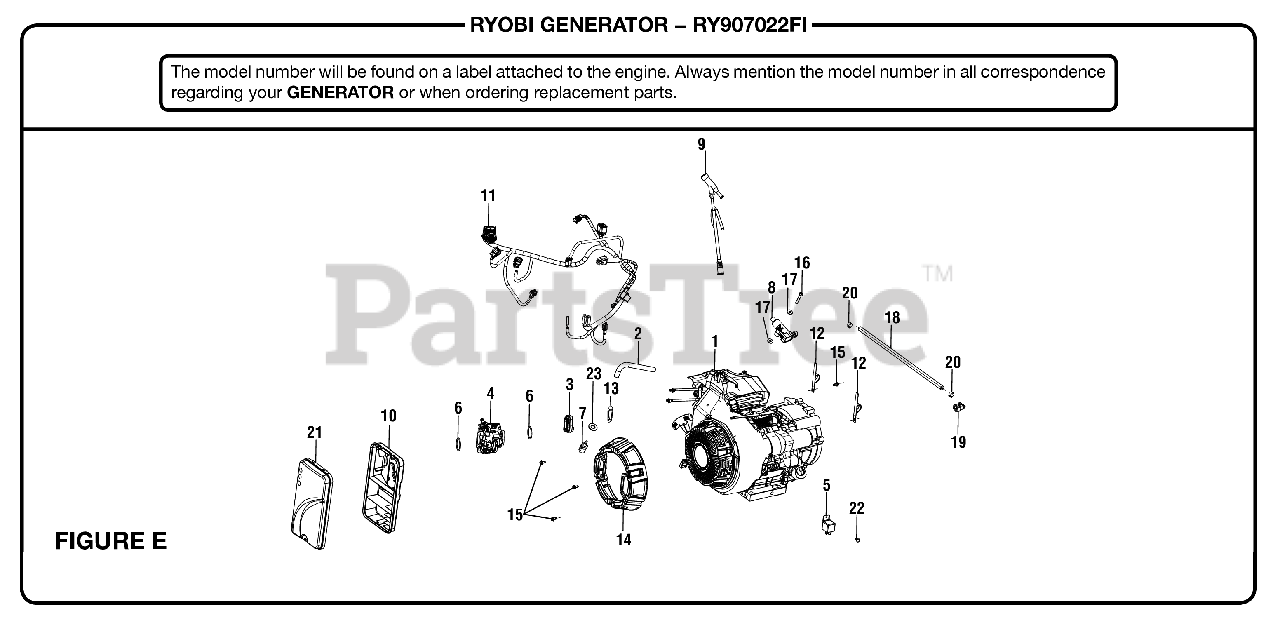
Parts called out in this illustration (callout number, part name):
1	R420 EFI Engine (Longblock
2	Crankcase Vent Hose
4	Throttle Body Assembly
5	Starter EFI Relay
7	Head Temperature Sensor
8	Ignition Coil
9	High Tension Wire Assembly
10	Rear Airbox w/ Bushings Assembly
11	EFI Wire Harness
12	J-Clamp Flexible
13	EFI Intake Gasket
14	Recoil Cover
15	Bolt (M5 x 10 mm, Flange Hex Hd.)
16	Bolt (M6 x 42 mm, T30 Torx Hex Hd.)..
17	Washer (OD17 x ID6.4 x 1.6t)
18	Fuel Hose (440 mm)
19	Fuel Quick Connect 90
20	Fuel Clamp
21	Front Airbox Cover
22	Bolt (M6 x 10mm, Hex Hd.)
23	Washer (1/2 in.)
